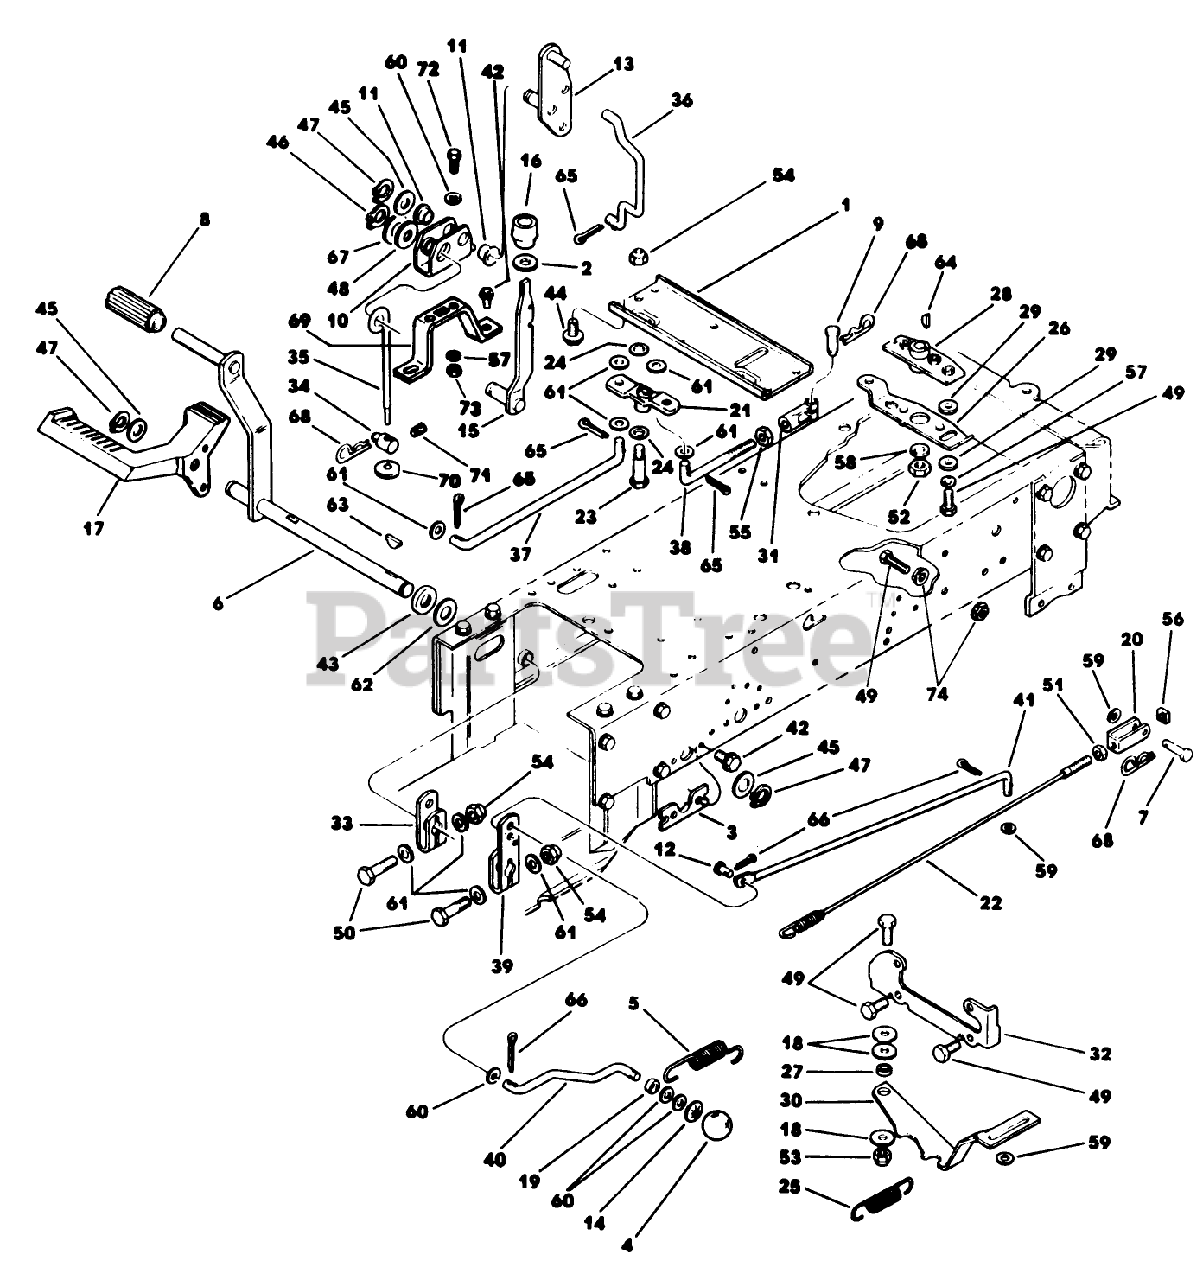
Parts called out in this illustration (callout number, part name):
19	Baffle-Housing, Blower
56	Nut, Square 1/4-20 Plated
57	Lock Washer 5/16 Plated
71	Set Screw, Hex Socket Hd. Cup Pt. #10-32 x 1/8
